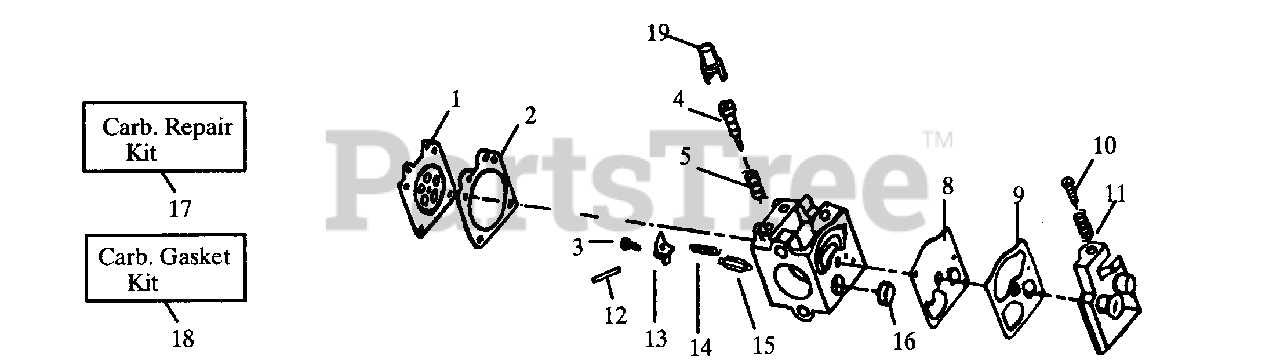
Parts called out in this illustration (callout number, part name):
1	Metering Diaphragm
2	WT-141 - T 1
2	WT-141A - T 2
3	Metering Lever Pin Screw
4	WT-141 - T 1
4	WT-141A - T 2
5	WT-141 - T 1
5	WT-141A - T 2
8	Fuel Pump Diaphragm
9	Fuel Pump Gasket
10	Idle Speed Screw
11	Idle Speed Spring
12	Metering Lever Pin
13	Metering Lever
14	WT-141 - T 1
14	WT-141A - T 2
15	Inlet Needle Valve
16	Fuel Inlet Screen
17	Carb. Kwik Repair Kit
18	Carb. Gasket/Diaphragm Kit
19	Limiter Cap (Gold)
